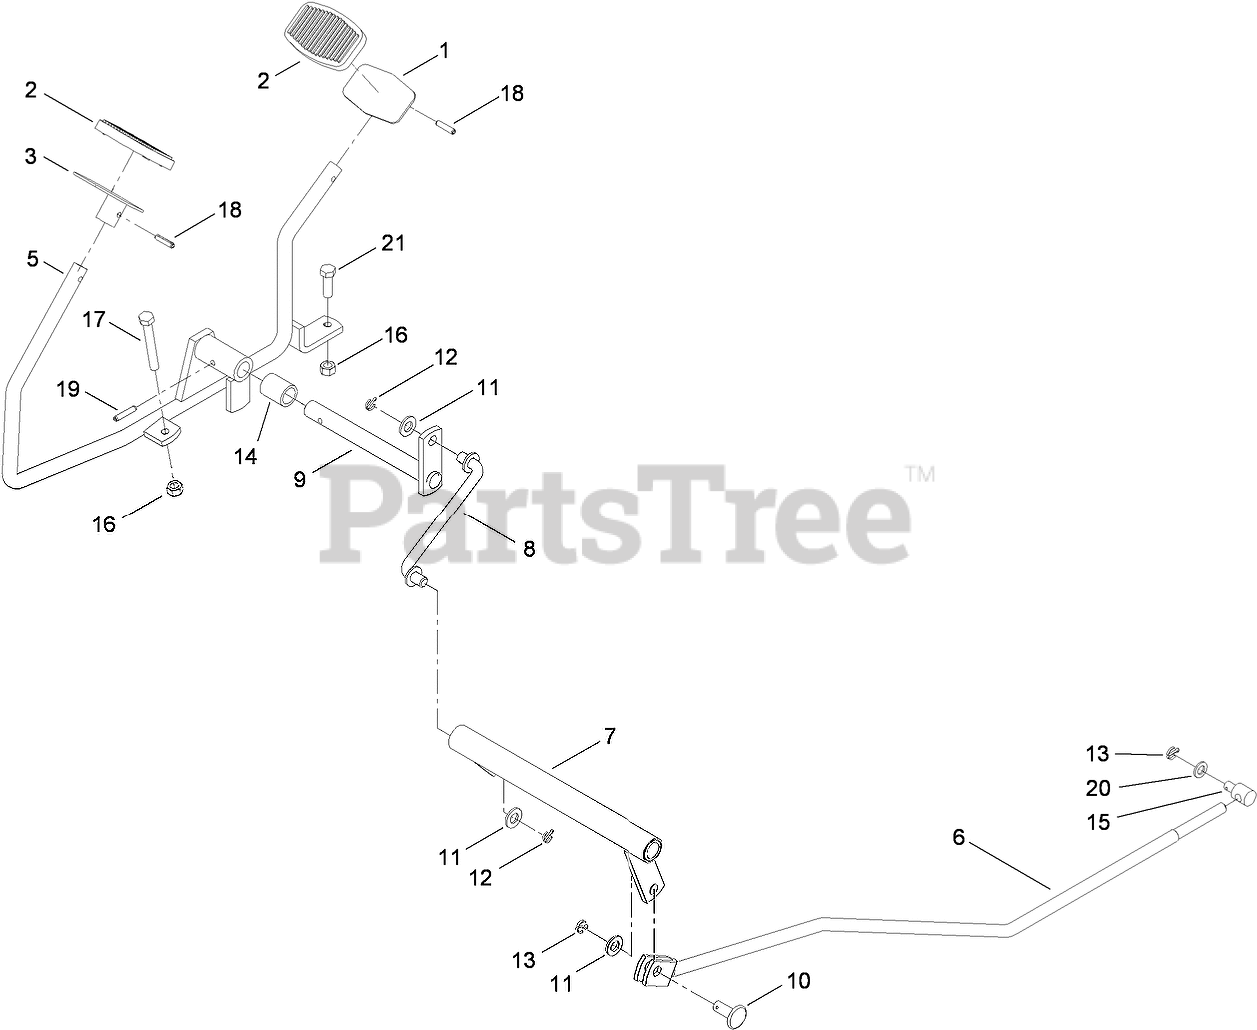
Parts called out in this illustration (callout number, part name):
1	PEDAL-REAR, TRAVEL
2	PAD-PEDAL
3	PEDAL-TRAVEL, FORWARD
5	ROD-TRAVEL
6	ROD-TIE
7	SHAFT-DIAGONAL
8	LINK-FORMED
9	SHAFT-DIAGONAL
11	WASHER-FLAT
12	PIN-COTTER
13	PIN-COTTER
14	SPACER
16	NUT-HEX
17	SCREW-HH
18	PIN-SPRING
19	PIN-SPRING
20	WASHER
21	SCREW-HH
